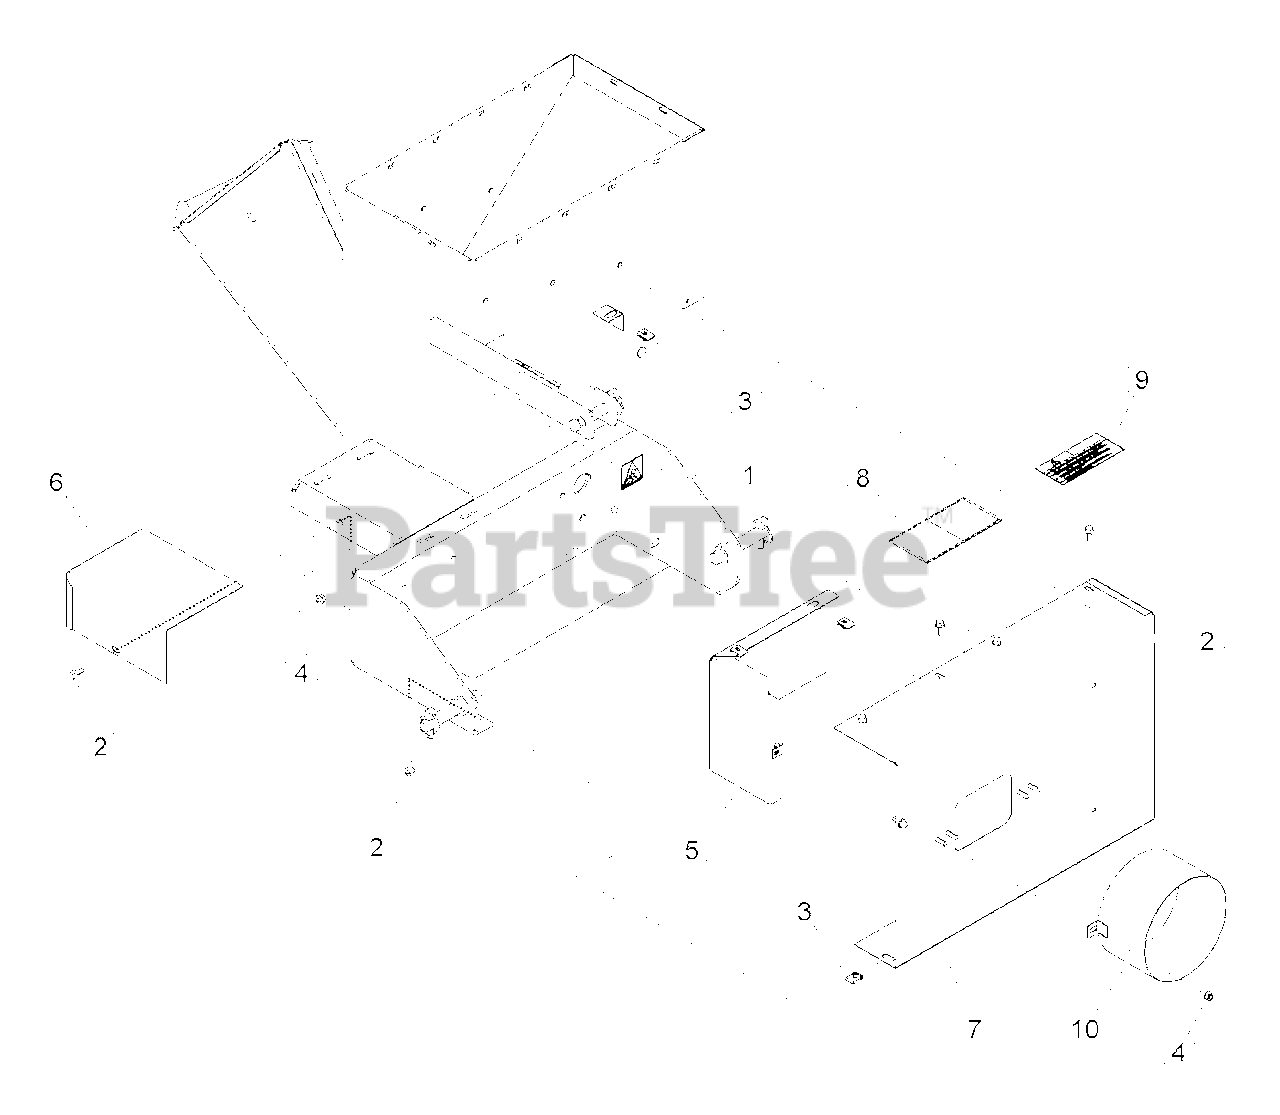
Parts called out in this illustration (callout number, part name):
1	DECAL, SHIELD DANGER ISO
2	BOLT, 5/16 X 3/4 FLANGE NC
3	NUT, 5/16"-18 TINNERMAN U-TYPE
4	NUT, 5/16-18 NYLOCK-FLANGE
5	GUARD, PTO END
6	WELDMENT, JACKSHAFT SHIELD
7	GUARD, BELT WITH DECAL 540
8	DECAL, PTO DANGER ISO
9	DECAL, MUTILINGUAL MANUAL
10	WELDMENT, PTO SHIELD
